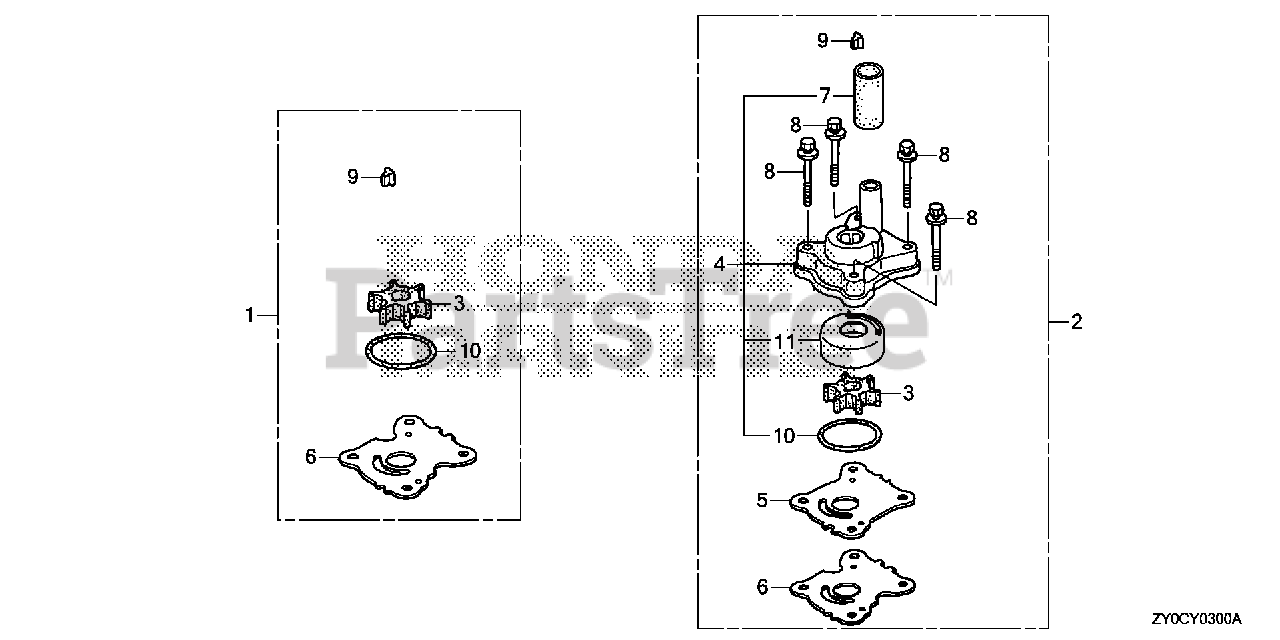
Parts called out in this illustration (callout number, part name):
1	PUMP KIT, IMPELLER
2	PUMP KIT, IMPELLER
3	IMPELLER, PUMP (UL)
4	HOUSING ASSY., IMPELLER
5	COVER, IMPELLER
6	GASKET, IMPELLER
7	RING, WATER TUBE SEAL
8	BOLT-WASHER (6X50)
9	KEY, WOODRUFF
10	O-RING (42.2X2.4)
11	LINER, PUMP
